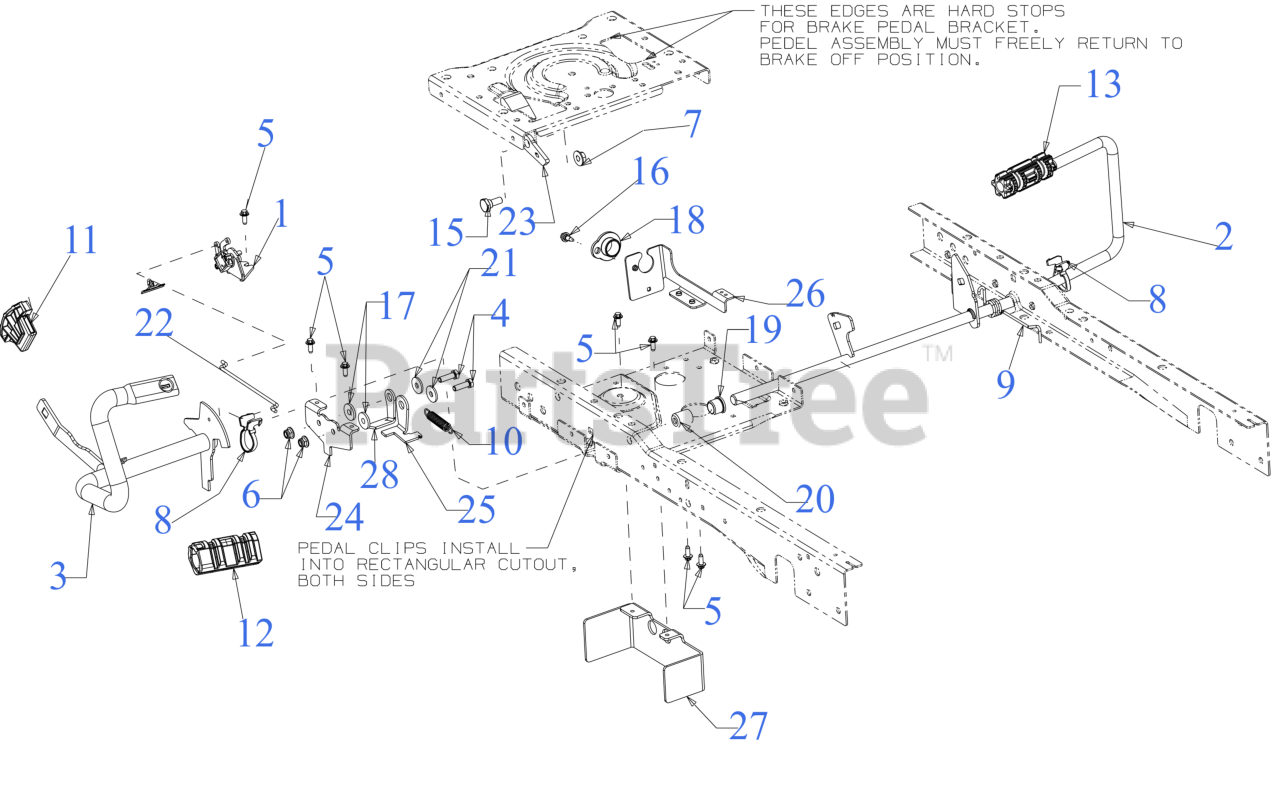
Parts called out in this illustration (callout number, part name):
1	THROTTLE SENSOR ASSEMLBLY
2	BRAKE PEDAL ASSEMBLY
3	PED ASM:FWD+REV:TUBE
4	SCREW 5/16-18 x 1.0 GR5
5	SCREW M6-1 x .625
6	FLANGE LOCK NUT 5/16-18
7	FLANGE LOCK NUT
9	TORSION SPRING .725
10	SPRING-EXT .51"DIA x 2.85"LG
11	REVERSE PEDAL PAD
12	FORWARD PEDAL PAD
13	BRAKE PEDAL PAD
15	SHOULDER SCREW
16	SHOULDER SCREW
17	SHOULDER SPACER (.315" x .50" x.14")
18	FLANGE BEARING
19	FLANGE BEARING .63x.84x.71
20	PLASTIC SLEEVE BEARING
21	THRUST BEARING (.323" x .985" x .1")
22	SWITCH ROD
23	CRUISE LATCH
24	NEUTRAL RETURN BRACKET
25	REVERSE RETURN BRACKET
26	BRAKE SWITCH BRACKET
27	RETURN COVER PLATE
28	BRKT:RTN:FWD
